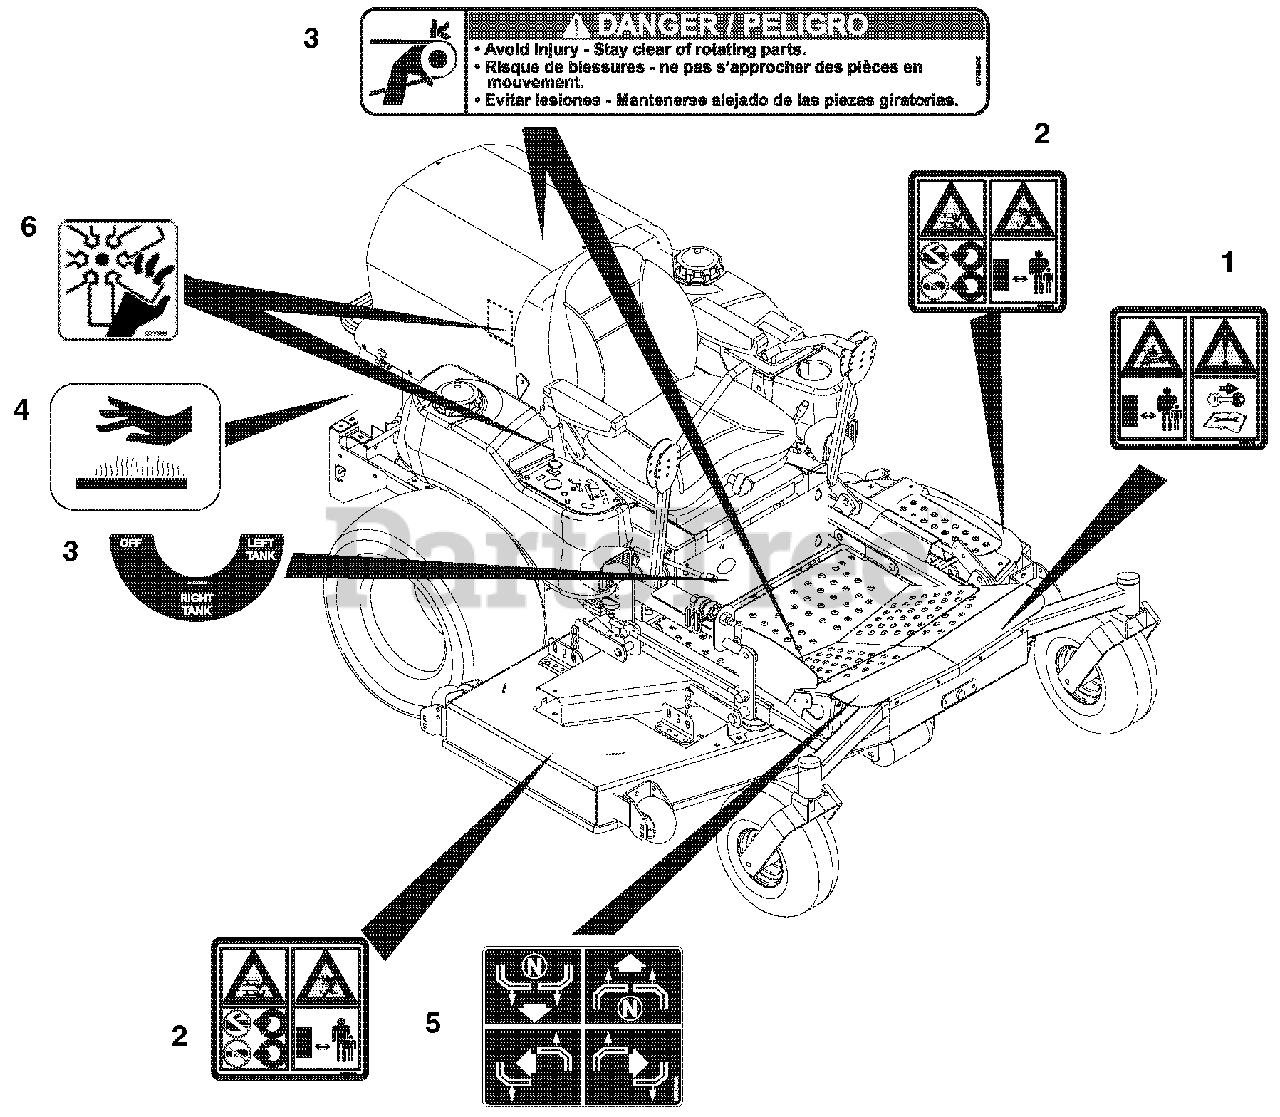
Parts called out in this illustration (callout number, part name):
1	Decal, CE Caution
2	Decal, CE Caution
3	Decal Set, Common Danger/Fuel
4	Decal, Hot Surface
5	Decal, Instructional
6	Decal, Danger Fan
